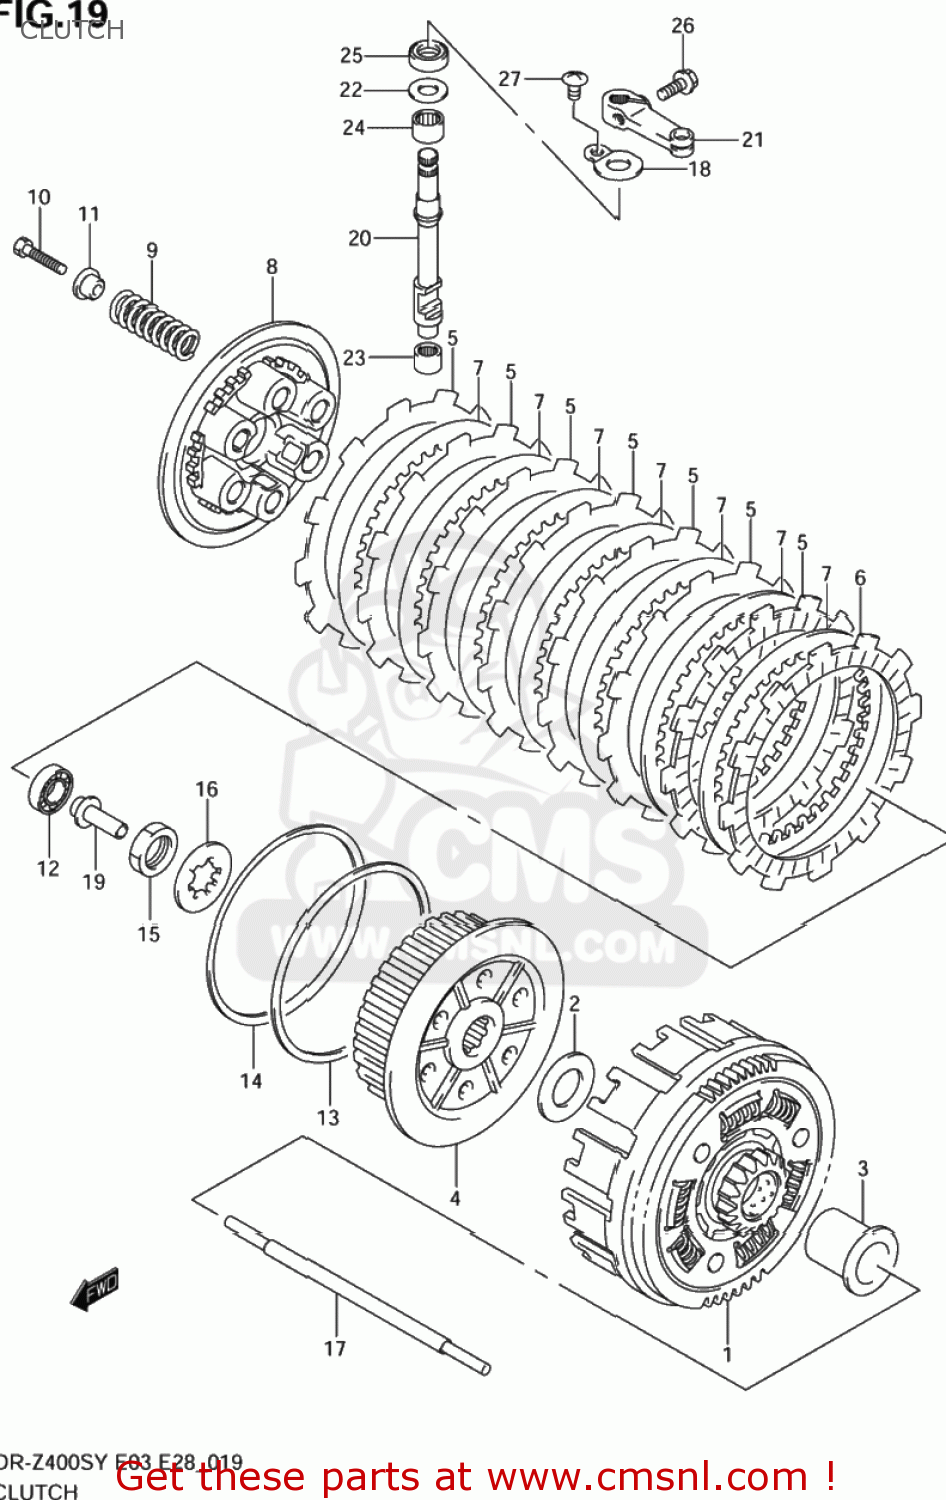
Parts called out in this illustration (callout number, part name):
1	GEAR ASSY,PRI DRIVEN
2	WASHER
3	SPACER,PRIMARY DRIVEN GEAR
4	HUB,CLUTCH SLEEVE
5	PLATE,CLUTCH DRIVE NO.1 (NAS)
6	PLATE,CLUTCH DRIVE NO.2 (NAS)
7	PLATE,CLUTCH DRIVEN (NAS)
8	DISC,CLUTCH PRESSURE
9	SPRING,CLUTCH
10	BOLT
11	WASHER
12	BEARING(12X28X8)
13	WASHER(112X122X1)
14	WASHER
15	NUT
16	WASHER,LOCK
17	ROD,CLUTCH PUSH
18	RETAINER,CL RLSE OIL SEAL
19	PIECE,CL PUSH
20	CAMSHAFT,CLUTCH RELEASE
21	ARM,CLUTCH RELEASE
22	SHIM(10X20X1)
23	BEARING(10X14X10)
24	BEARING(12X16X10)
25	SEAL,OIL(10X20X6)
26	BOLT
27	SCREW 6X10
